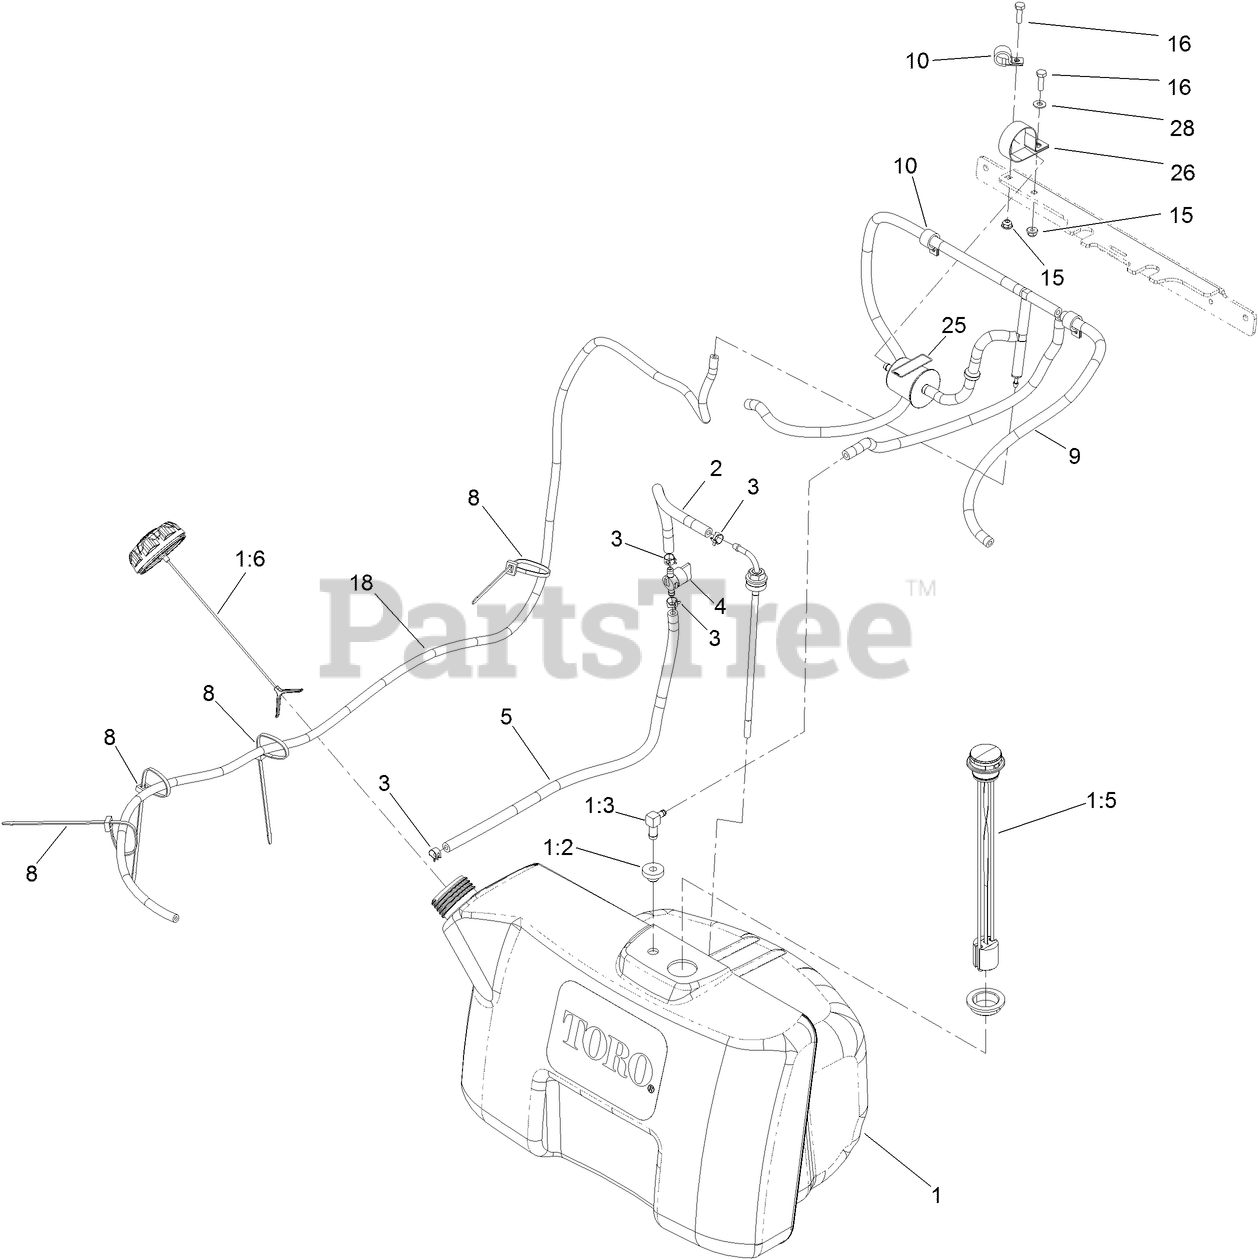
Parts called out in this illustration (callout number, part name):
1	TANK ASM
1:2	BUSHING
1:3	ELBOW-90 DEG
1:5	CAP-FUEL, RATCHETING
1:6	FITTING-FUEL, BULKHEAD
2	HOSE-FUEL
3	CLAMP-HOSE
4	VALVE-FUEL
5	HOSE-FUEL
8	TIE-CABLE
9	VENT HOSE ASM
10	CLAMP-CABLE
15	NUT-HF
16	SCREW-HH
18	HOSE-FUEL
25	DECAL-FILTER, EMISSIONS
26	CLAMP-R
28	WASHER-FLAT
